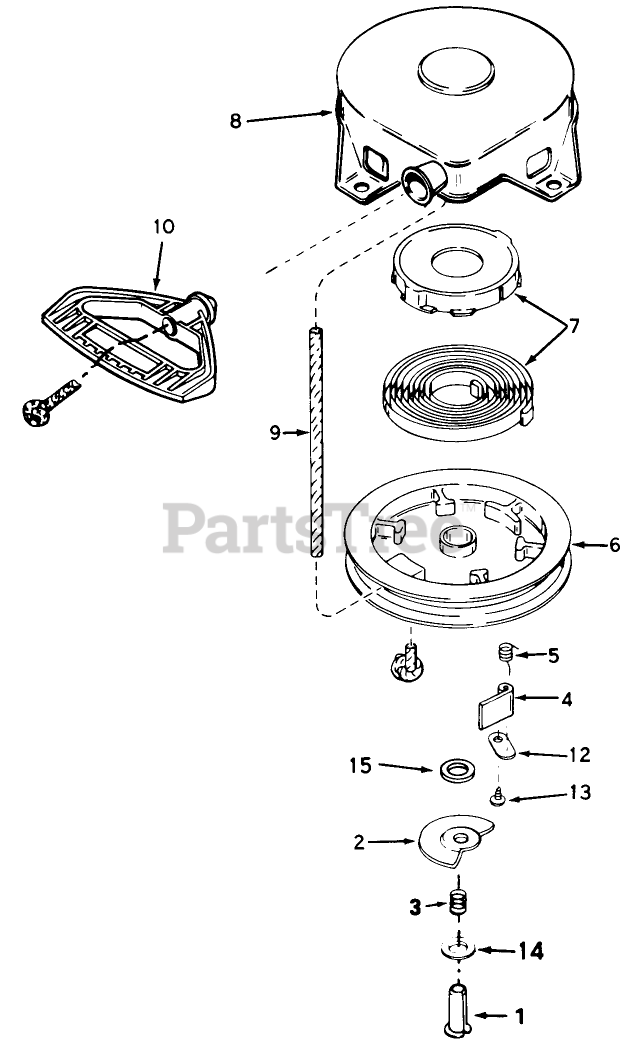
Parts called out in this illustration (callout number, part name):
1	Pin, Spring (Incl. Ref. #7)
2	Washer
3	Brake Spring
4	Dog-Starter
5	Spring-Dog
6	Pulley
7	Spring Keeper Assy
8	Housing-Starter
9	Rope-Starter
10	Handle-Starter, Mitten Grip
12	Retainer-Dog
13	Screw
14	Washer
15	Washer
